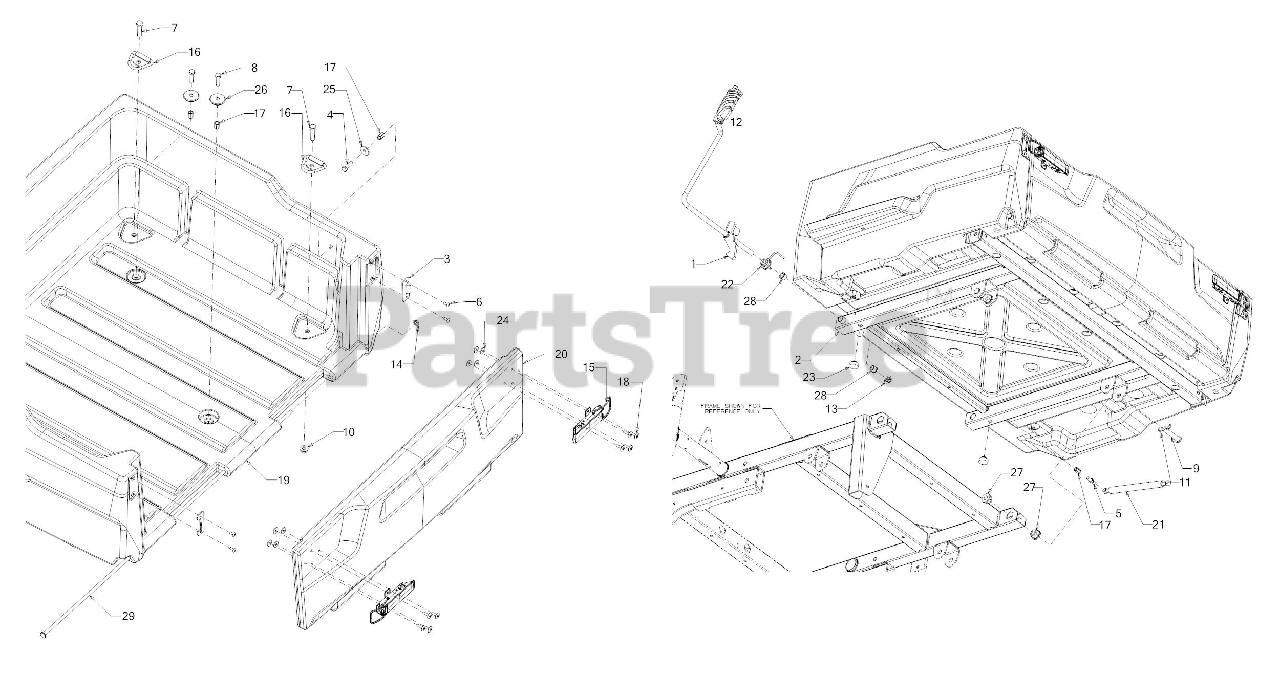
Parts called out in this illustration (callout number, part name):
1	BED LATCH ASSEMBLY (LH)
2	BED FRAME ASSEMBLY
3	TAILGATE LATCH BRACKET
4	SCREW 5/16-18 x 1.0 GR5
5	BALL STUD 5/16-18
6	SCREW #10-24 x .500
7	SCREW 3/8-16 x 1.50
8	SCREW 5/16-18 x 1.25 GR5
9	CLEVIS PIN .494 x 2.528
11	BOW TIE COTTER PIN
14	PUSH CAP
15	OVER CENTER DRAW LATCH
16	TIE DOWN MOUNT
17	NUT RIVET 5/16-18
18	POP RIVET - .188 DIAMETER
21	7.87 STROKE GAS SPRING
22	TORSION SPRING
23	RUBBER BUMPER 1.000 x .313
24	FLAT WASHER .194x.620x.063
25	FLAT WASHER 1.0 OD:.331 ID
26	SHOULDER SPACER
27	FLANGE BEARING
28	FLANGE BUSHING
29	TAIL GATE ROD
